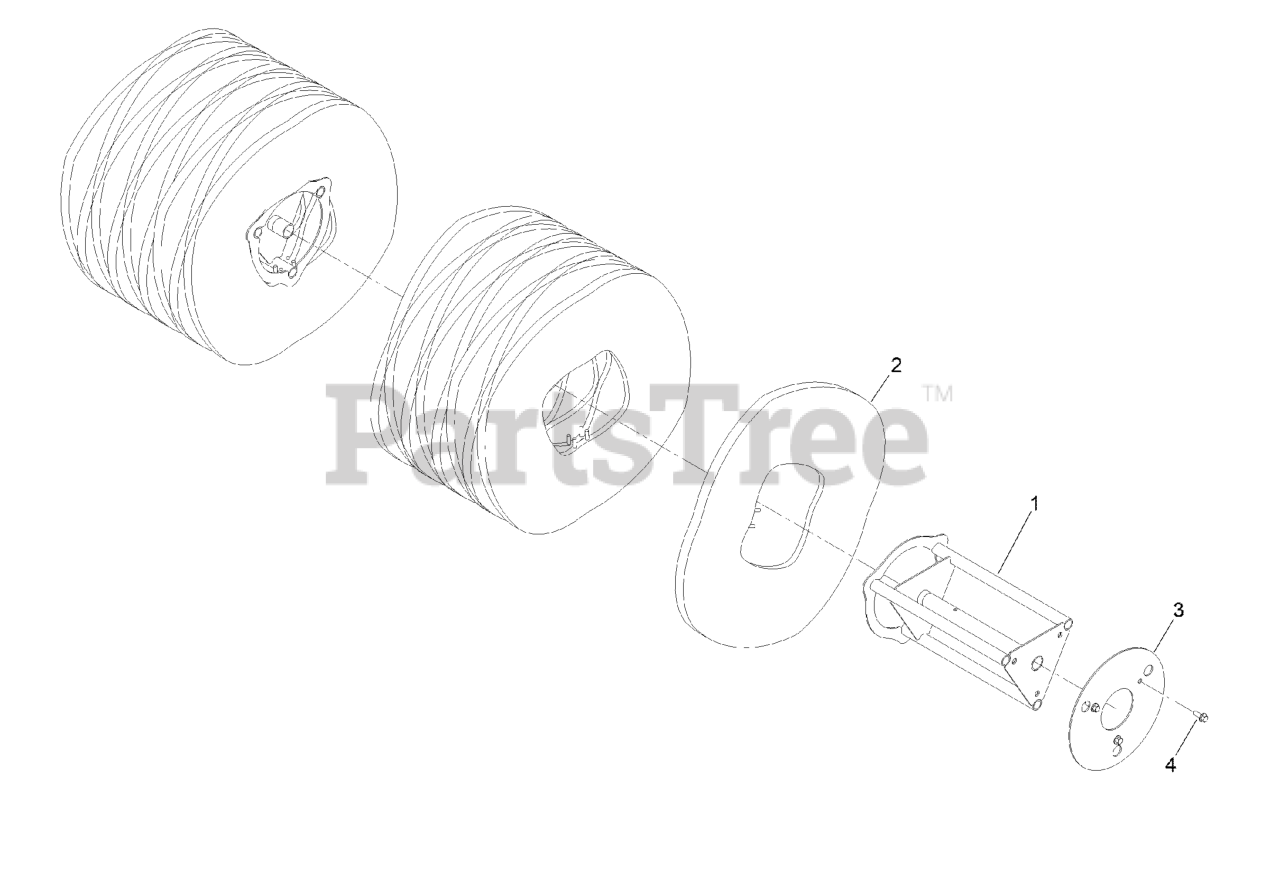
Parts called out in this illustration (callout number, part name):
1	CORE-BROOM
2	SEGMENT-POLY
3	PLATE-END, RETAINER
4	SCREW-HHF
